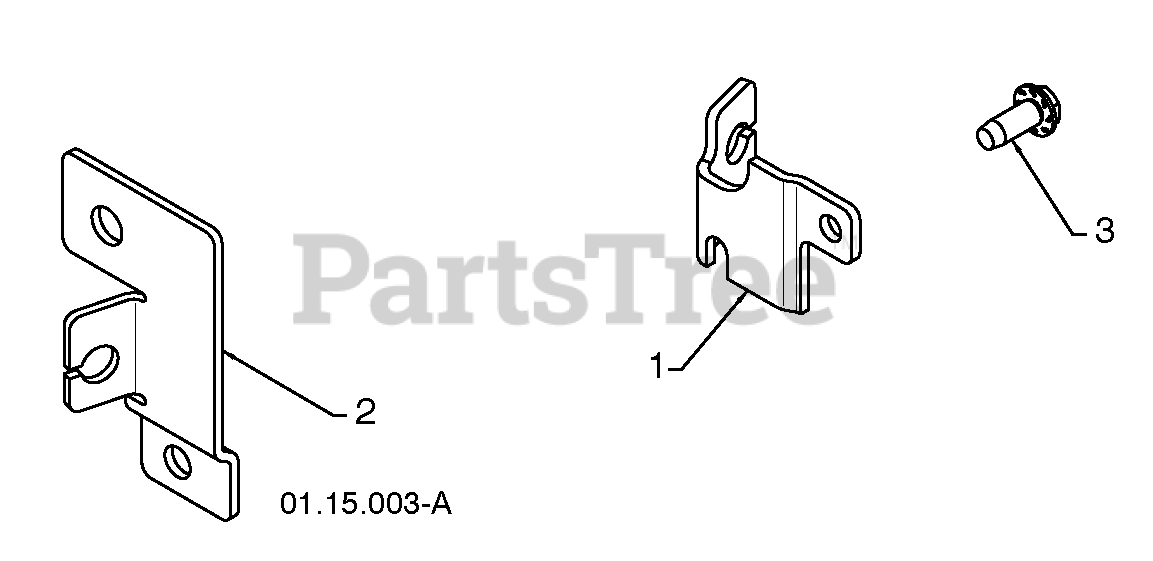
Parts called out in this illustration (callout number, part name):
1	CABLE BRACKET LH
2	CABLE BRACKET RH
3	SCREW 1/4-20 X .625
